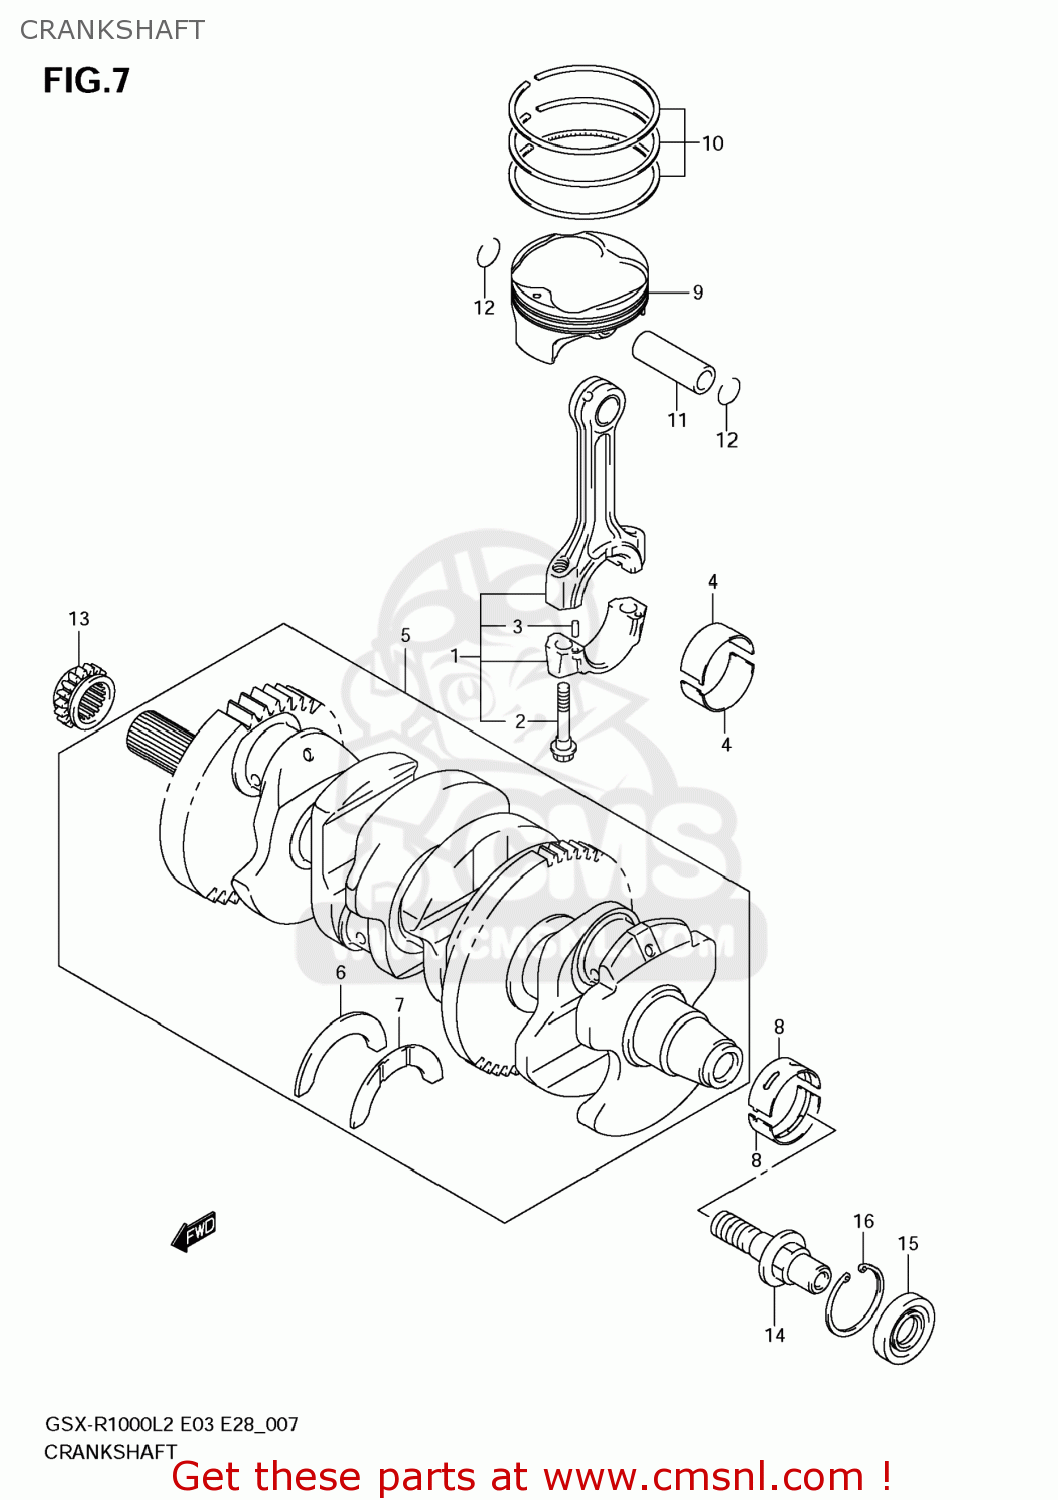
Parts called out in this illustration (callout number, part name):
1	CONNECTING ROD ASSY
2	BOLT,CONNECTING ROD
3	PIN,CONNECTING ROD
4	BEARING,CRANK PIN
5	CRANKSHAFT SET
6	BEARING,CRANK THRUST(GREEN)
7	BEARING,CRANK THRUST(RED)
8	BEARING,CRANKSHAFT
9	PISTON
10	RING SET,PISTON
11	PIN,PISTON
12	CIRCLIP
13	SPROCKET,CAM CHAIN DRIVE
14	BOLT,GENERATOR ROTOR
15	SEAL,OIL(14X30X8)
16	CIRCLIP
